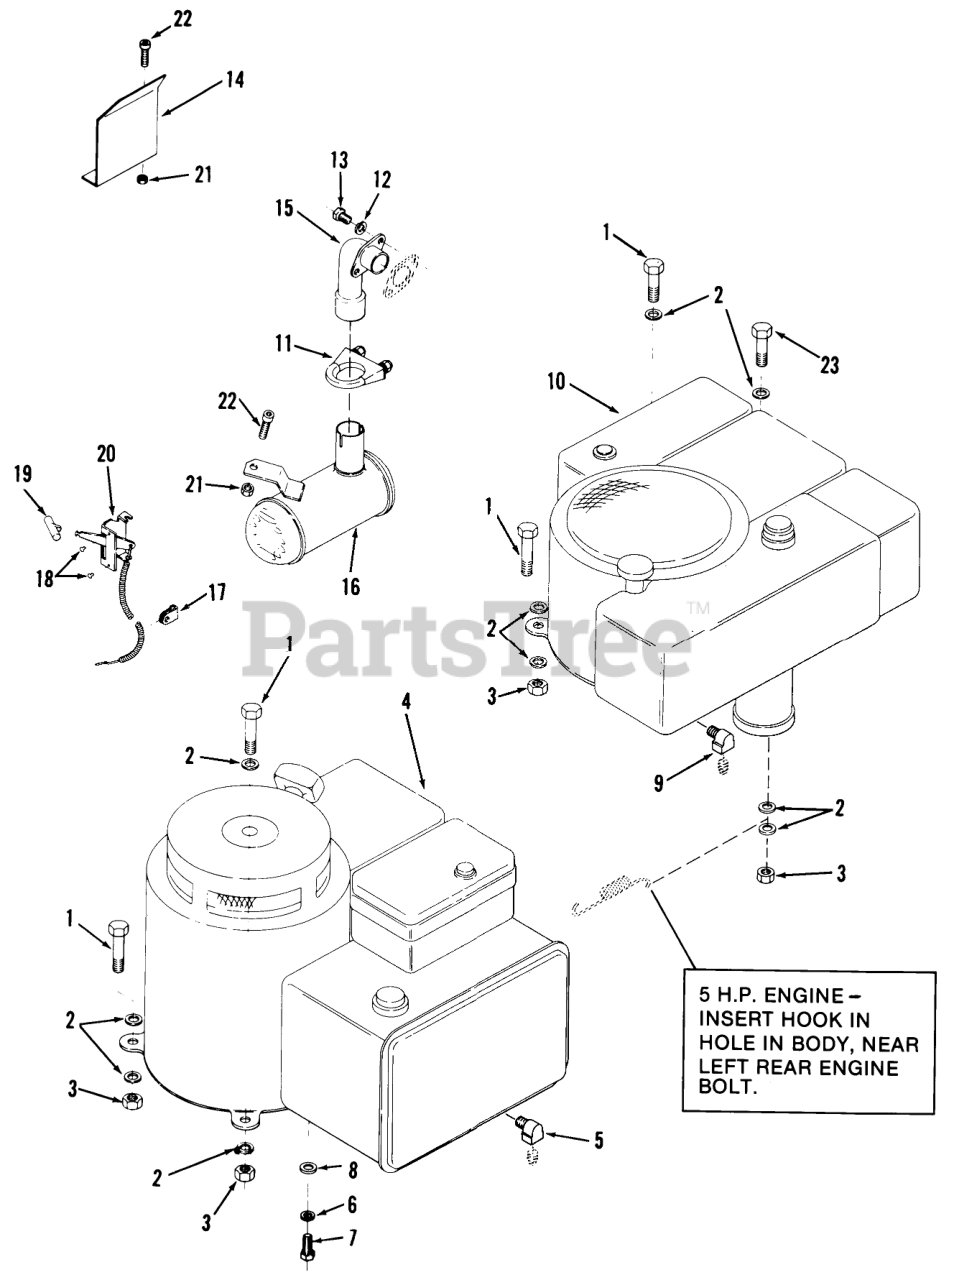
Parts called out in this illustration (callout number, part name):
2	WASHER 5/16 SAE
2	WASHER
4	Engine 5 H.P.-B S Model 130902 Type 0584-01
5	Street Elbow
10	Engine 8 H.P.-B S Model 191707 Type 5663-01 A-81 Only
10	Engine 11 H.P.-B S Model 252707 Type 0207-01 A-111 Only
10	Engine 8 H.P.-B S Model 191702 Type 5648-01 A-81R Only
17	THROTTLE CONTROL CLP
18	RIVET
22	SHCS 5/16-18X.625
